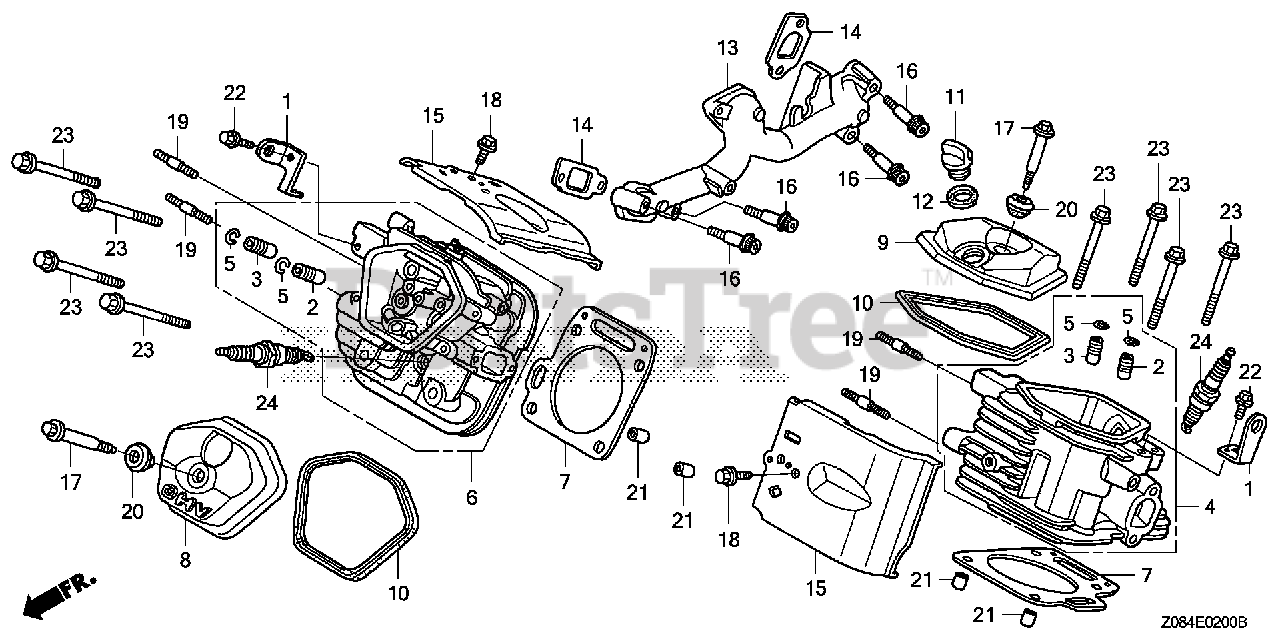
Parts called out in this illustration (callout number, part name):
1	HANGER, ENGINE
2	GUIDE, VALVE (OVER SIZE)
3	GUIDE, EX. VALVE (OVER SIZE)
4	CYLINDER HEAD (#1)
5	CLIP, VALVE GUIDE
6	CYLINDER HEAD (#2)
7	GASKET, CYLINDER HEAD
8	COVER, HEAD
9	COVER, HEAD FILLER
10	GASKET, HEAD COVER
11	CAP, OIL FILLER
12	GASKET, OIL FILLER CAP
13	MANIFOLD, IN.
14	GASKET, IN. MANIFOLD
15	SHROUD, HEAD
16	BOLT, SOCKET (8X45)
17	BOLT, HEAD COVER
18	BOLT, FLANGE (6X14) (CT200)
19	BOLT, STUD (8X22)
20	WASHER, HEAD COVER
21	PIN, DOWEL (12X20)
22	BOLT, FLANGE (8X20)
23	BOLT, FLANGE (10X80)
24	SPARK PLUG (BPR2ES) (NGK)
24	SPARK PLUG (J14CR-U) (DENSO)
24	SPARK PLUG (ZGR4A)
24	SPARK PLUG (J16CR-U) (DENSO)
24	SPARK PLUG (ZGR5A)
